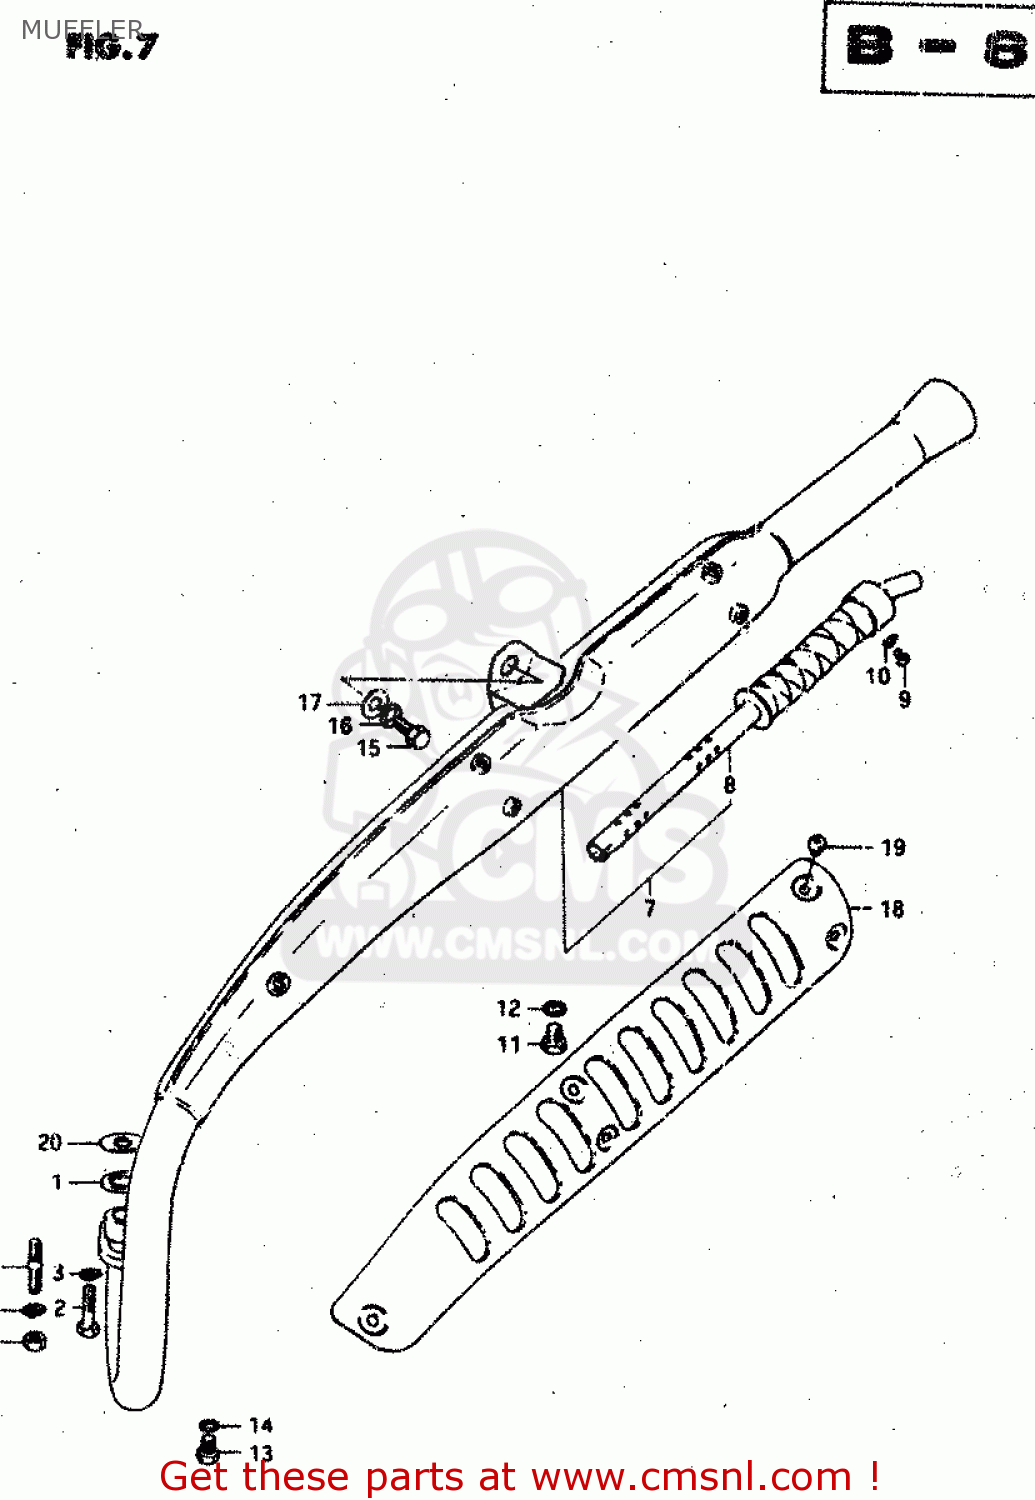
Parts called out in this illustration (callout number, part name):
1	GASKET,EXHAUST PIPE (MCA)
2	BOLT(8X27)
3	LOCK WASHER
4	STUD BOLT
5	NUT
6	LOCK WASHER
7	MUFFLER ASSY
8	PIPE,BAFFLE
9	SCREW
10	LOCK WASHER
11	BOLT 10X9
12	GASKET(10X14X3.6) (NAS)
13	BOLT(6X8)
14	GASKET(6.2X11X1).2 (NAS)
15	BOLT
16	LOCK WASHER
17	WASHER
18	COVER,MUFFLER
19	SCREW,6X6
20	PLATE, EXHAUST PIPE
